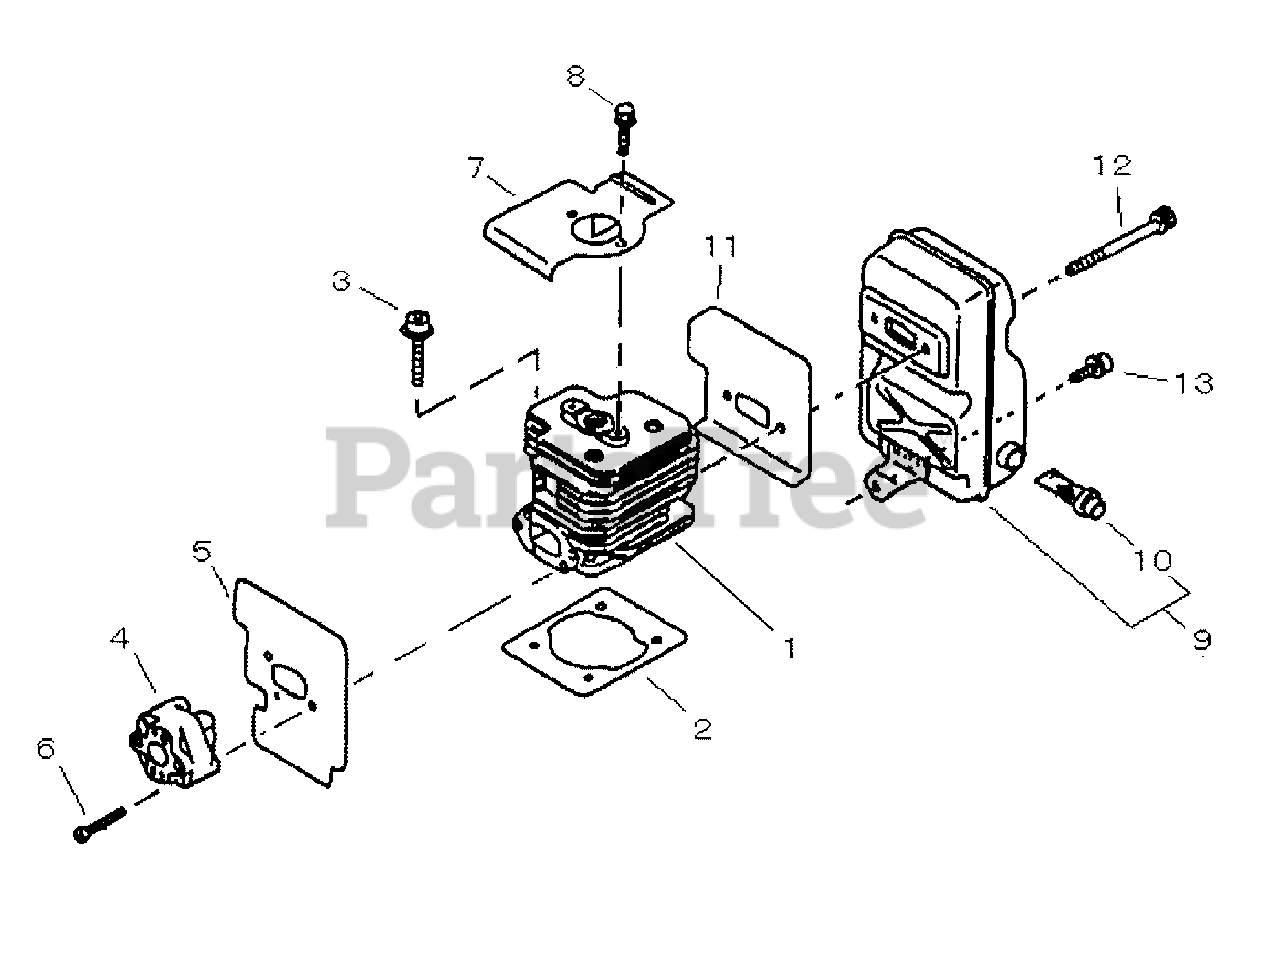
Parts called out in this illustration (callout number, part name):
1	CYLINDER
2	GASKET, CYLINDER
3	BOLT - 5X22
4	INSULATOR
5	GASKET, INTAKE
6	SCREW - 5X35
7	SHIELD, CYLINDER
9	MUFFLER ASSY
10	SCREEN, SPARK ARRESTOR
11	GASKET, EXHAUST
12	SCREW - 6X70
13	BOLT - 6X12 -- FLANGE
